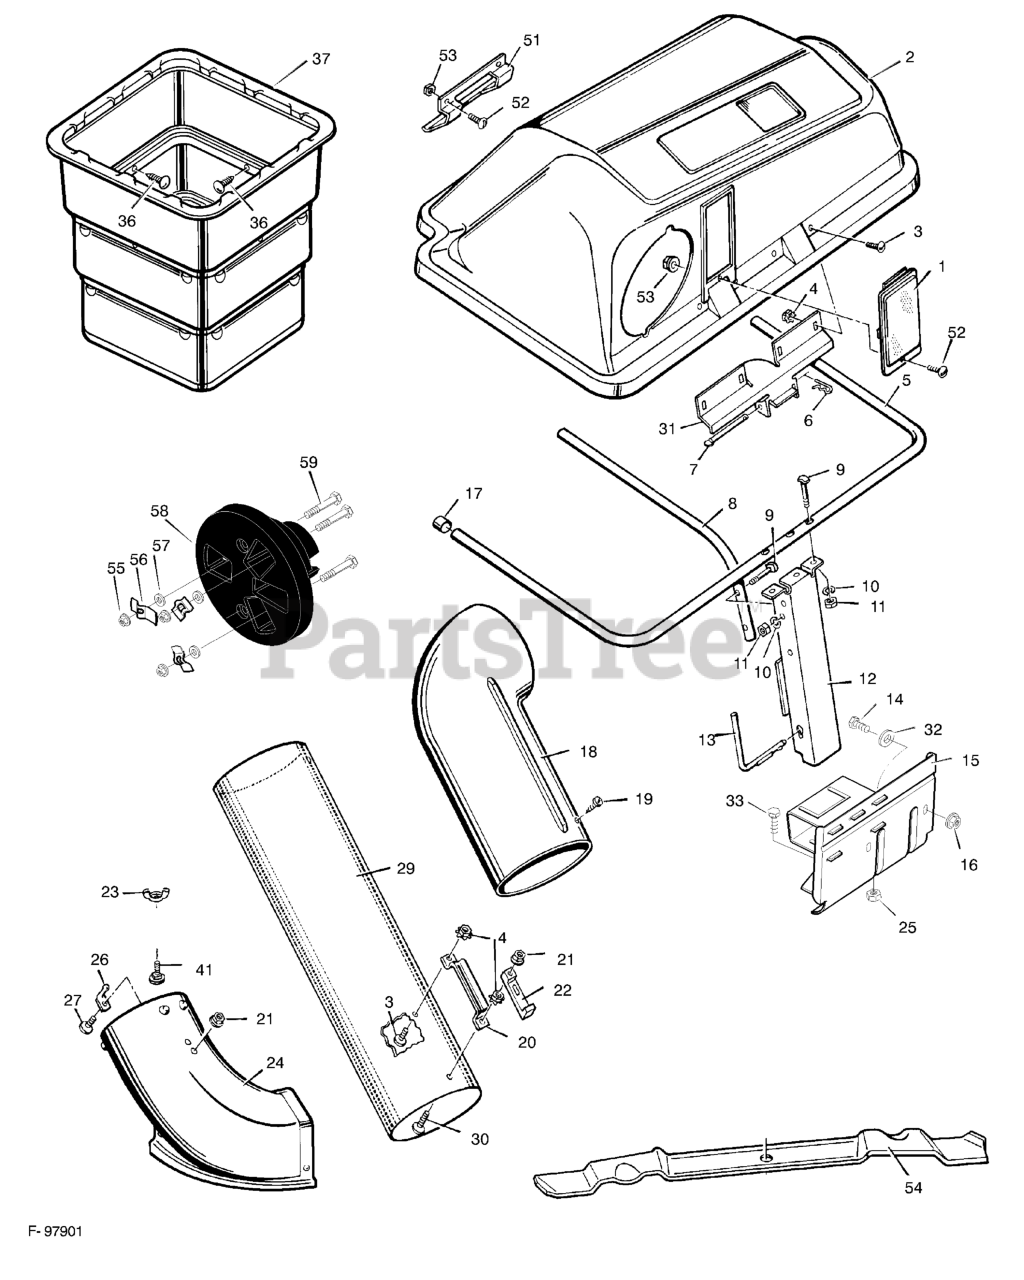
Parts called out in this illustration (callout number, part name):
4	Locknut
6	Pin, Hair
7	Pin, Hinge
8	Tube, Center
9	Bolt, Special
10	Lockwasher
11	Nut, Hex
12	Channel Assembly
13	Pin, Channel
14	CAPSCREW, Hex Head, 5/16-18 x 1
15	Mount Assembly, Bagger
16	Nut, Hex
17	Cap, End
20	HANDLE, Connect Tube
21	Locknut, Flange
22	Latch, Rubber
23	Wingnut
24	Tube, Extension
25	Hex Nut
26	Pin, Latch
27	Bolt, Carriage
29	Tube, Connector
31	Hinge, Cover
33	Bolt, Hex
36	Fastener, Plastic
37	Containers (Quantity 2)
41	Bolt, Carriage
51	Handle, Plastic
53	Nut, Hex
54	Blade, High Lift (97cm)
55	Nut, Flange
56	Clip, Wheel
57	Retainer
58	Weight, Wheel
